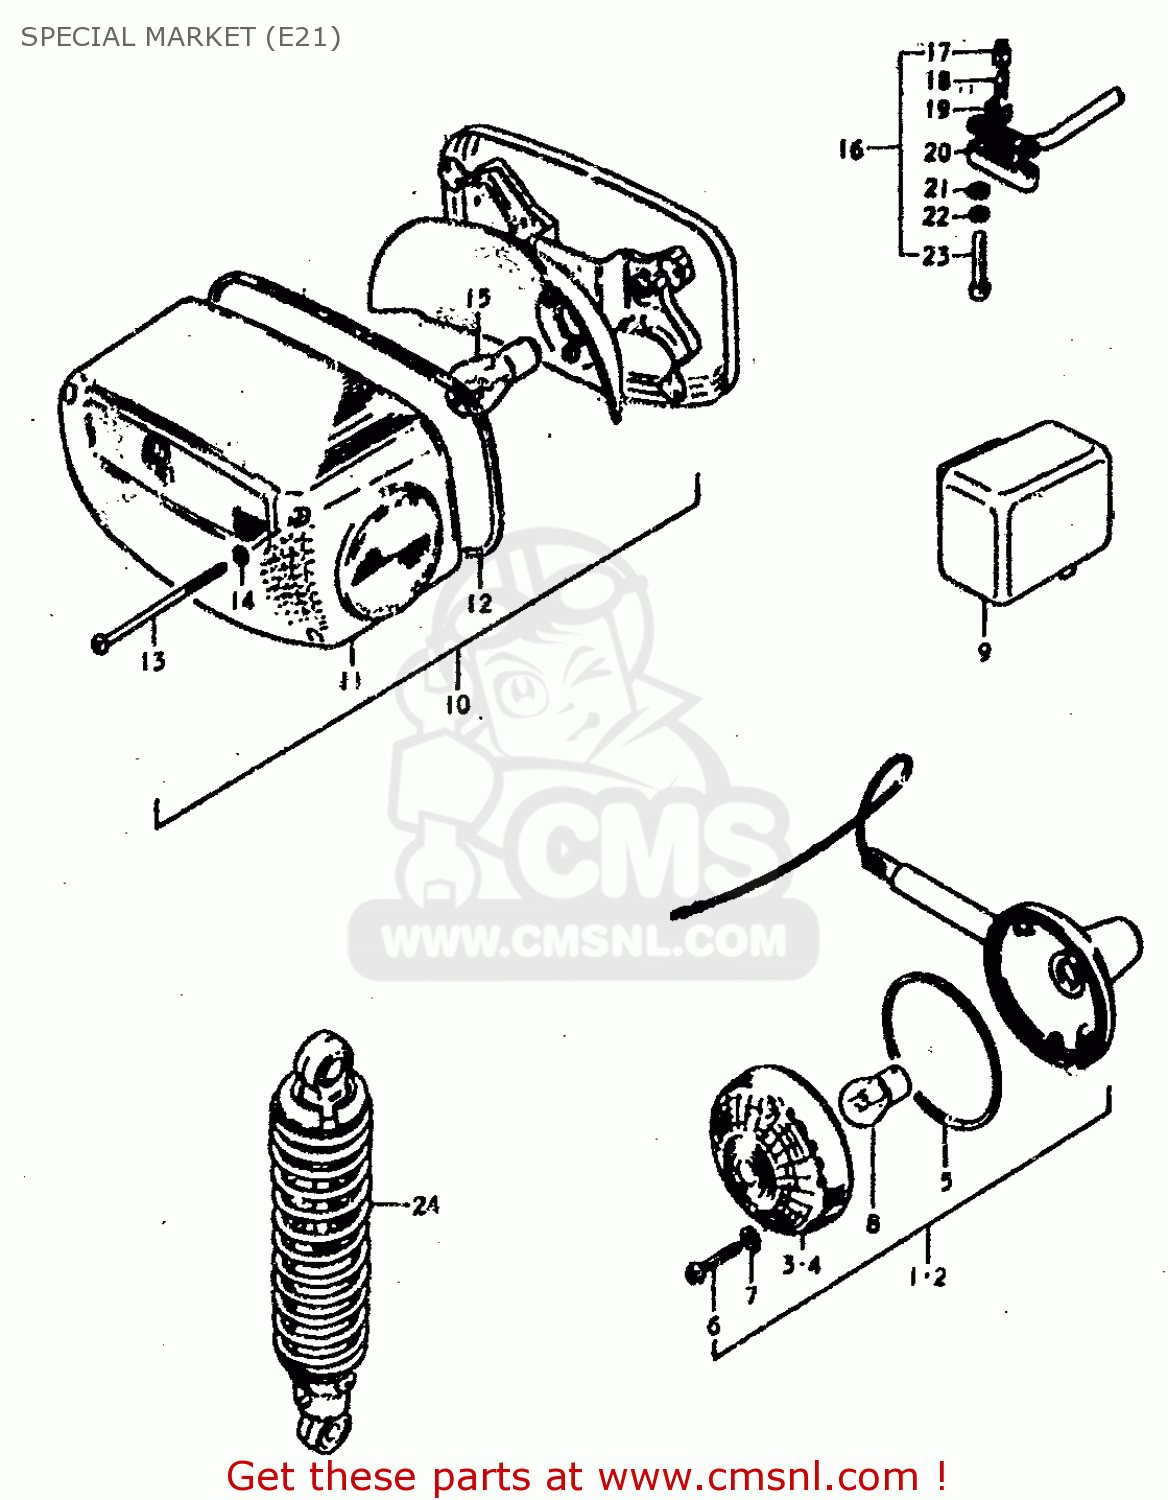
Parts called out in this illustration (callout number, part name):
1	LAMP ASSY, FRONT TURN SIGNAL
2	LAMP ASSY, REAR TURN SIGNAL
3	LENS
4	LENS
5	GASKET (NAS)
6	SCREW
7	GASKET (NAS)
8	BULB 12V 21W
10	LAMP ASSY, REAL COMBINATION
11	LENS,REAR COMBINATION LAMP
12	GASKET (NAS)
13	SCREW (4X55)
14	GASKET (NAS)
15	BULB
16	SWITCH ASSY,STOP
17	HOLDER
18	SPRING
19	PLATE
20	COVER,FR BK TERMINAL BASE
21	WASHER
22	LOCK WASHER
23	SCREW
24	SHOCK ABSORBER,REAR
